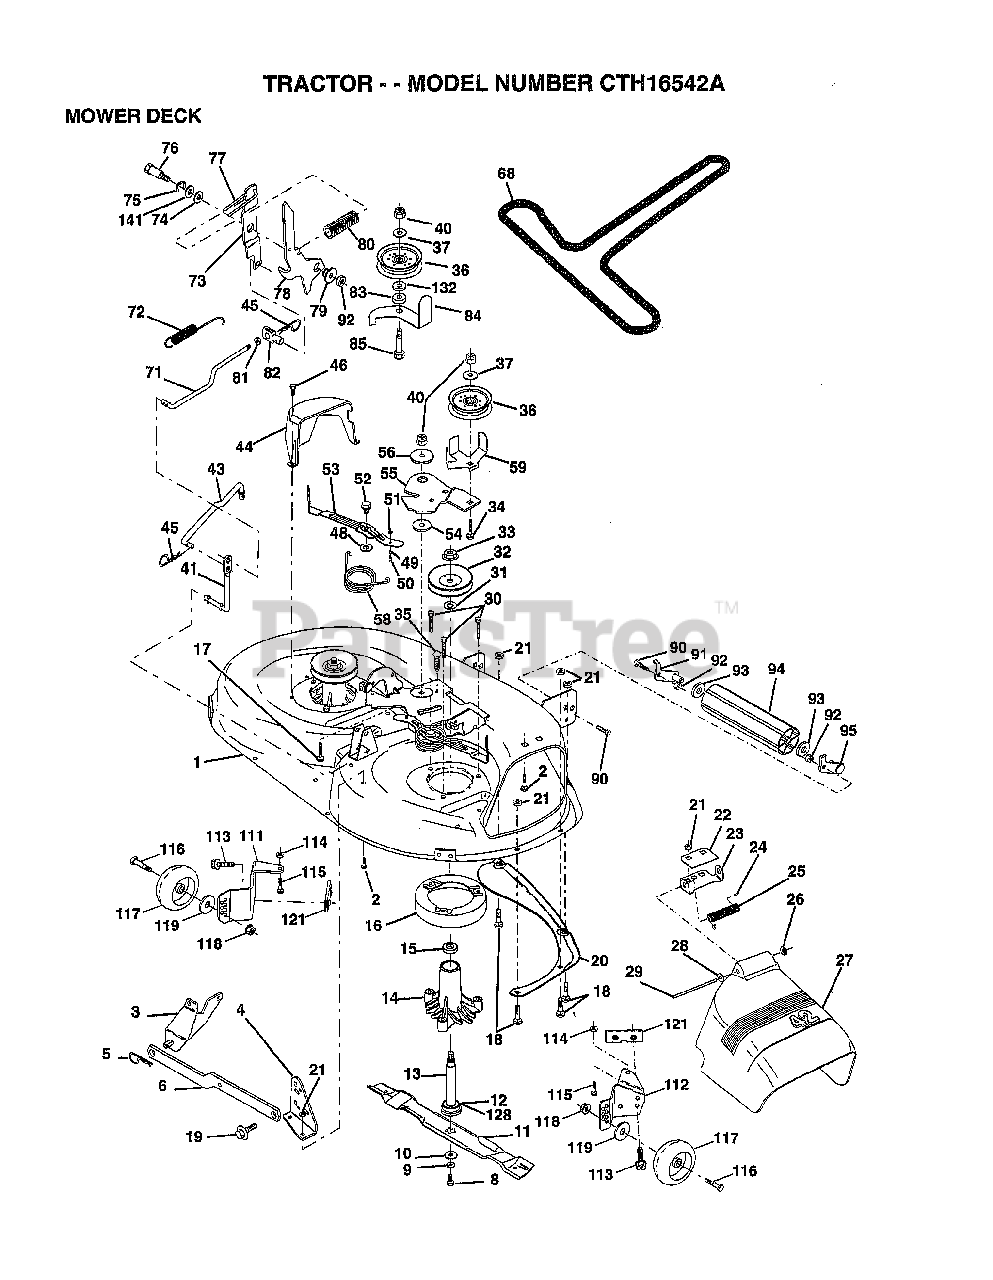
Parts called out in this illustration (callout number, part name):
1	DECK.WELD.42.
2	BOLT
3	BRKT ASM SWAY BAR
4	BRKT DECK SW BAR
8	BLADE BOLT
10	WASHER.HARD.BLADE
11	"BLADE.42"" HIPERF"
12	BEARING.BALL
14	HSG ASM MANDREL
15	BEARING
16	STRIPPER RND MWR
17	BOLT RDHD 3/8-16
18	BOLT
19	BOLT SHD 5/16-18
20	BAFFLE VORTEX 42
22	STIFFENER BRKT
23	DEFLECTOR BRKT
25	SPRING TORSION
27	DEFLECTOR.SHIELD
28	WASHER
29	HINGE ROD
30	"SCREW-THD ROLL,WA"
31	WASHER
32	PULLEY.MANDREL.42
34	BOLT
35	XMAS TREE FASTNER
36	FLAT IDLER PULLEY
37	WASHER
41	PIVOT ROD
43	ROD CLUTCH W/NIBS
44	GUARD MAND LH BLK
46	SCREW.1/4-20X5/8
48	HARD SMALL WASHER
49	ROLLER ASM-CAM
50	SHOULDER BOLT
51	LOCKNUT
52	BOLT.SHLD.5/16-18
53	BRAKE PAD ARM ASM
54	HARDENED WASHER
55	ARM-IDLER
56	SPACER RETAINER
58	SPRING TORSN BRAK
59	GUARD IDLER TUV
68	BELT.V.T-PATH
71	ROD CLUTCH 38/42
72	SPRING.EXT.RETURN
73	CLUTCH ARM SECOND
74	WASHER
75	RING
76	SHOULDER BOLT
77	SPRING KEEPER
78	ARM CLUTCH PRIMARY
79	BUSHING
80	SPRING.CLUTCH.MWR
81	NUT
82	TRUNION ADJ
83	WASHER
84	"KEEPER-BELT,FIXED"
85	BOLT RDHD 3/8-16
90	BOLT
92	NUT
93	WASHER
111	BRACKET.GWHL.LH.
112	BRACKET.GWHL.RH.
113	SCREW
116	BOLT.SHOULDER
117	WHEEL.GUAGE.MED.
118	LOCKNUT
119	WASHER
121	BRACKET.EXTRD.GWL
128	WASHER.FELT.
132	WASHER GT
141	WASHER .T
